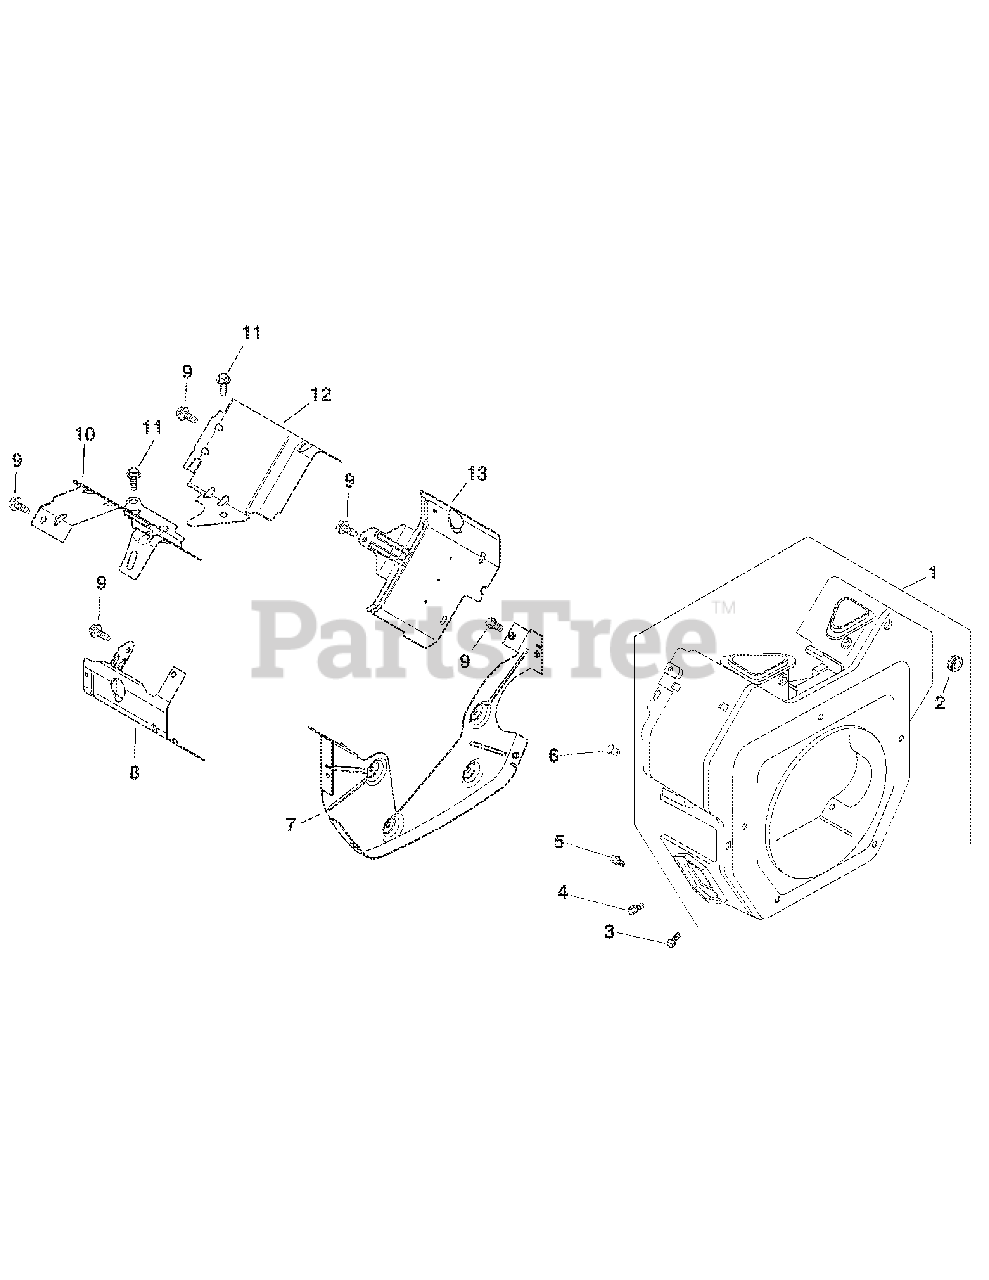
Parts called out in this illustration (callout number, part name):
1	Housing, blower (Includes 2, KH-41-037-10-S)
3	Screw, hex. Flange M5x0.8x16
4	Nut, plastic (2)
4	Screw, hex. Flange M5x0.8x16 (3)
5	Screw, hex. Flange M5x0.8x20 (2)
6	Insert, Threaded
7	Plate, backing (Includes KH-25-154-11-S)
8	Baffle, cylnd barrel - #2 side
9	Screw, hex. Flange M6x1.0x16 (6)
10	Baffle, valley - #2 side
11	Screw, hex. Flange M5x0.8x10 (2)
12	Baffle, valley - #1 side
13	Baffle, cylinder barrel -#1 side
